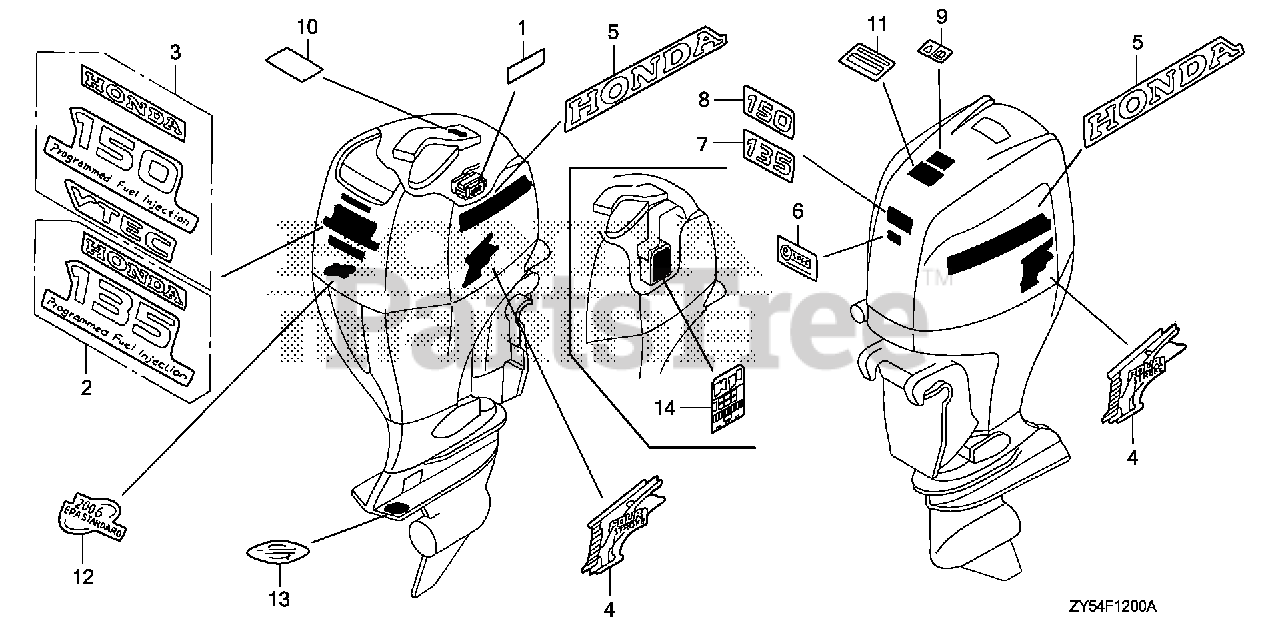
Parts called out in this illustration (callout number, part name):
1	LABEL, FUSE
2	MARK, RR. (135)
4	MARK, SIDE
5	MARK, SIDE STRIPE
6	MARK (E-SPEC)
7	MARK, FR. EMBLEM (135)
10	LABEL, OIL CAUTION (E)
11	LABEL, OPERATOR CAUTION (ENGLISH)
11	LABEL, WARNING OPERATOR
